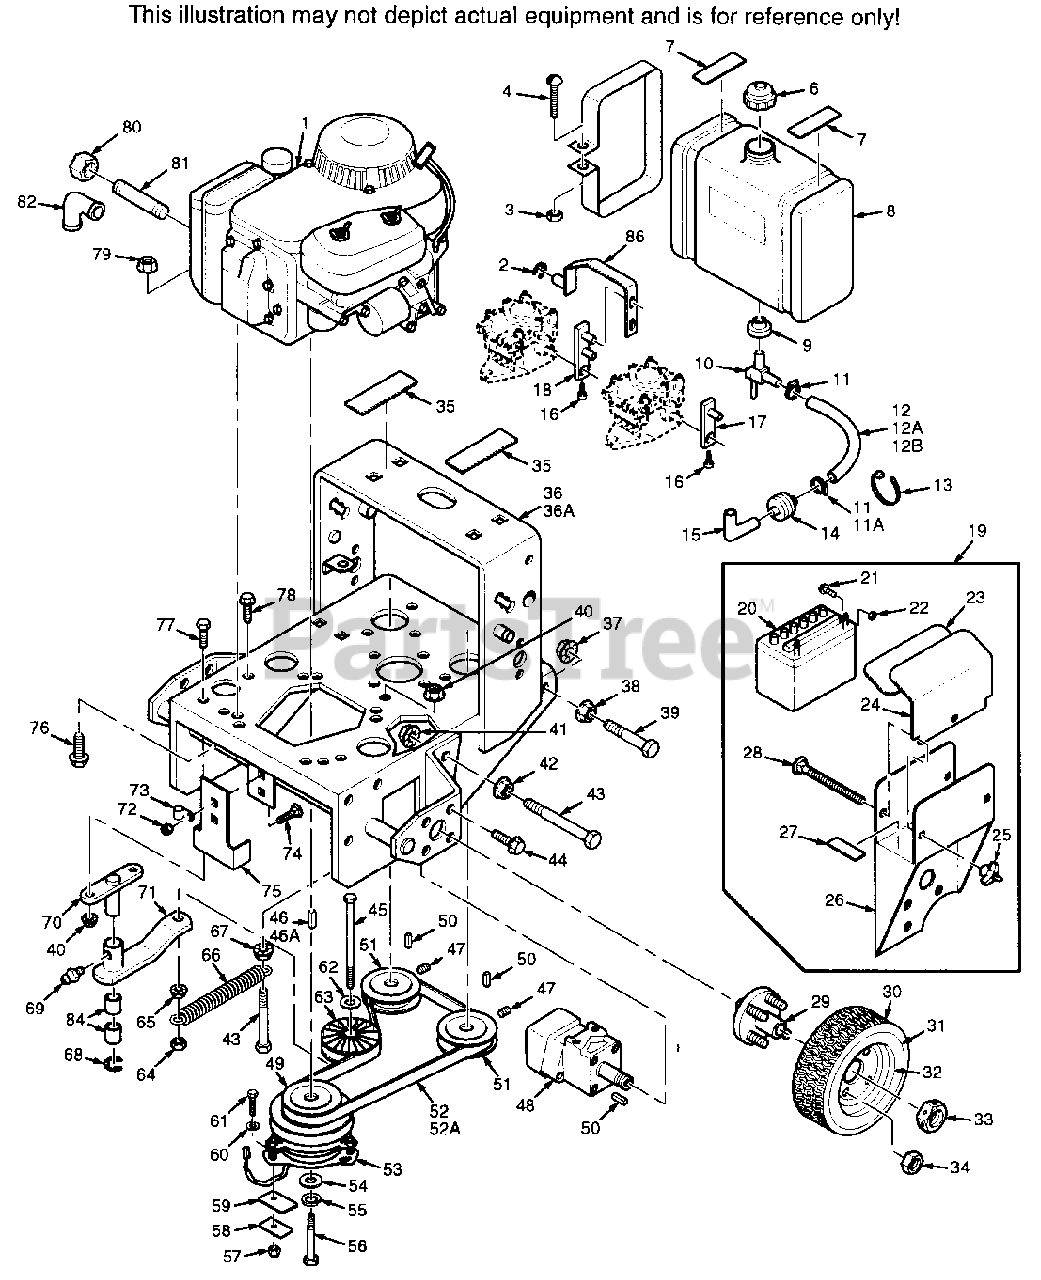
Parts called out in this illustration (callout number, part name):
2	RETAINING RING, 1/2"
4	MACHINE SCREW, 1/4-20 X 2 ROUND HD. SLOTTED
5	STRAP, FUEL TANK
6	CAP, FUEL TANK
7	PAD, RUBBER - FUEL TANK, UPPER
8	FUEL TANK ASSEMBLY(INCLUDES ITEMS 9, 10)
9	BUSHING
10	VALVE, FUEL SHUT-OFF
11	CLAMP, FUEL HOSE
13	CABLE TIE
16	CAPSCREW, # 10-32 X 1 SOC. HD.
17	LEVER ASSY, PUMP CRTL.
18	LEVER ASSY. PUMP CONTROL-RH
30	WHEEL ASSEMBLY(INCLUDES 31, 32, 29, 34)
35	PAD, RUBBER-FUEL TANK, LOWER
38	5/16-18, NUT, HH
40	5/16-18 SERR. FL. HEX NUT
41	3/8-16 SERR. FL. NUT
42	3/8-16 SERR. FL. NUT
44	3/8-16 X 1 SERR. FL. CAPSCREW
47	SETSCREW, 5/16-18 X 3/8 SOCKET HD.
48	MOTOR, WHITE RS
49	PULLEY, PUMP DRIVE - ENGINE
50	KEY, 3/16 X 3/16 X .75
51	PULLEY, PUMP SHAFT
53	ELECTRIC CLUTCH
54	FLATWASHER, 7/16
58	BACKING PLATE, CLUTCH STOP
59	RUBBER PAD, CLUTCH STOP
63	PULLEY, IDLER - PUMP DRIVE
65	NUT, 3/8-16 SERR. FL.
66	SPRING, PUMP BELT IDLER
67	NUT, SERR. FL.
68	RETAINING RING, 3/4 EXT. - "E"
69	GREASE FITTING
70	PIVOT, IDLER ARM
71	IDLER ARM
72	NUT, ELASTIC STOP, 3/16-18
74	CARRAGE BOLT, 5/16-18 X 1
75	CLUTCH BRACKET
78	BOLT, 5/16-18 X 1 SERR. FL.
79	HEX NUT, SERR. FL.
